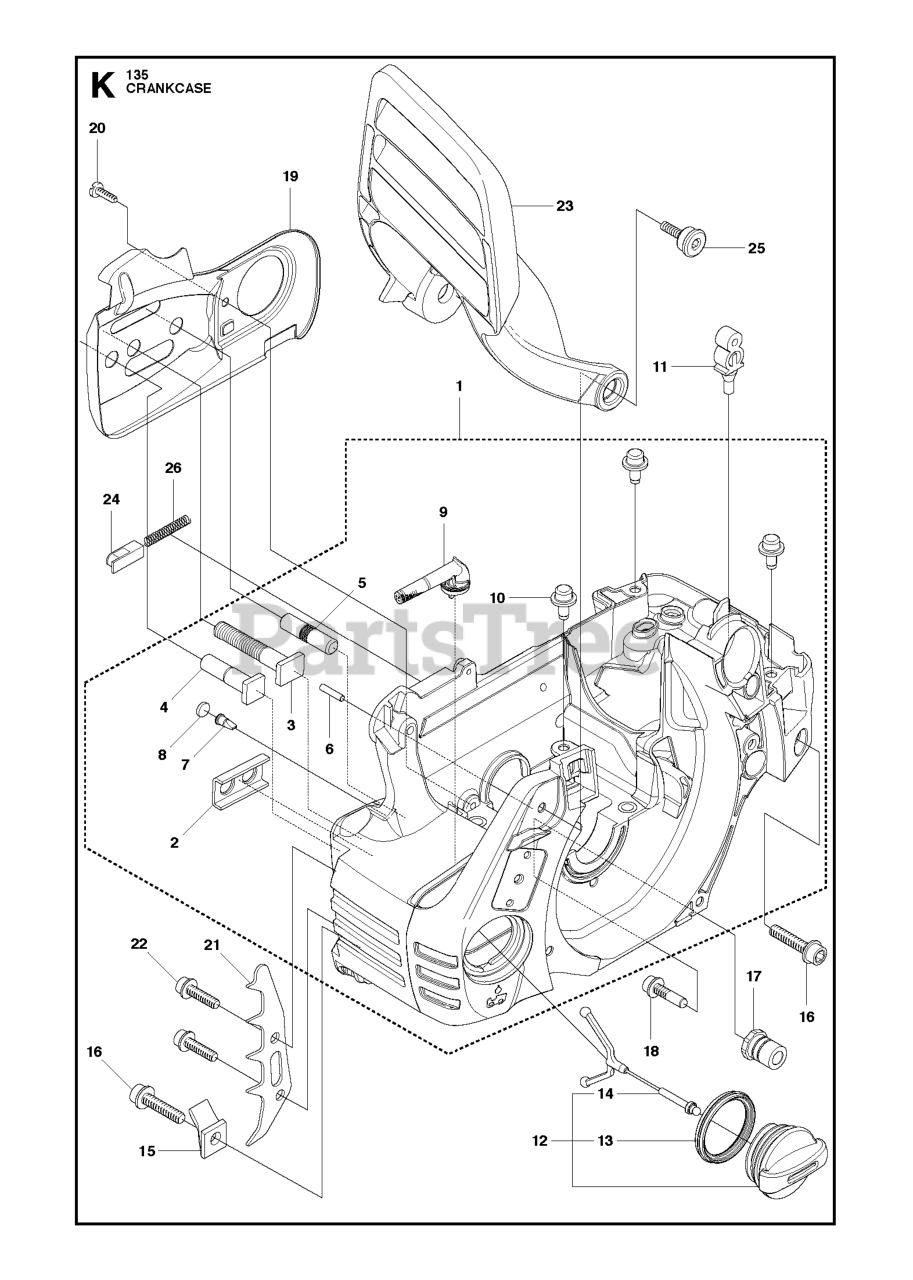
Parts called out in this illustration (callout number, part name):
1	CRANKCASE ASSY
2	STIFFENING PLATE
3	BAR BOLT
4	BAR BOLT
5	BAR BOLT
6	PIN
7	VALVE-CHECK (DUCKBILL)
8	PLUG
9	OIL SCREEN
10	GUIDE PEN
11	SUPPORT
12	ASSY TANK CAP GREY
13	SEALING
14	TANK LOCK
15	CHAIN CATCHER
16	SCREW
17	LATERAL SUPPORT
18	SCREW IHSCFT
19	CHAIN GUIDE PLATE
20	SCREW
21	SPIKE INNER
22	SCREW
23	HAND GUARD
24	CATCH
25	SCREW
26	LOCK SPRING
